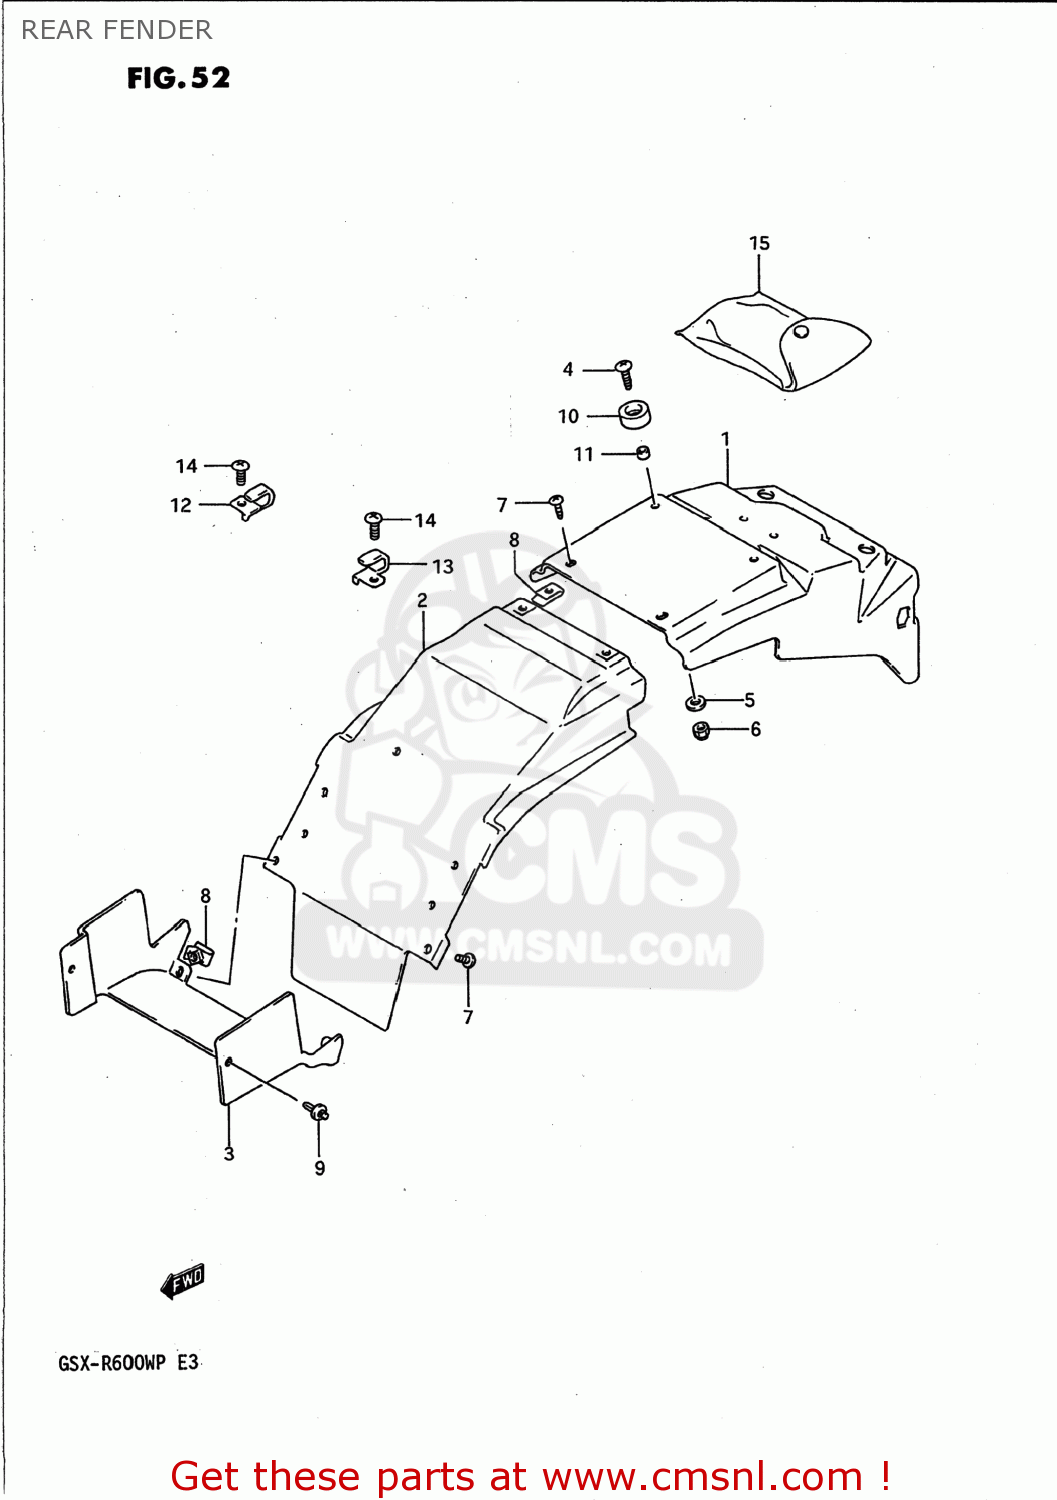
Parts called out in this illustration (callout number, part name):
1	FENDER,RR UPR
2	FENDER,REAR,UPPER,FRONT,N
3	FENDER,REAR,UPPER,FRONT,N
4	SCREW, CENTER
5	WASHER
6	NUT
7	SCREW, FRONT & REAR
8	NUT,HEADLAMP HOUSING,UPPER
9	CLIP
10	CUSHION,TAIL COVER UPR
11	SPACER (6.8X10X4.7)
12	HOLDER,HELMET,R
13	HOLDER,HELMET,LEFT
14	SCREW 6X12
15	TOOL ASSY
